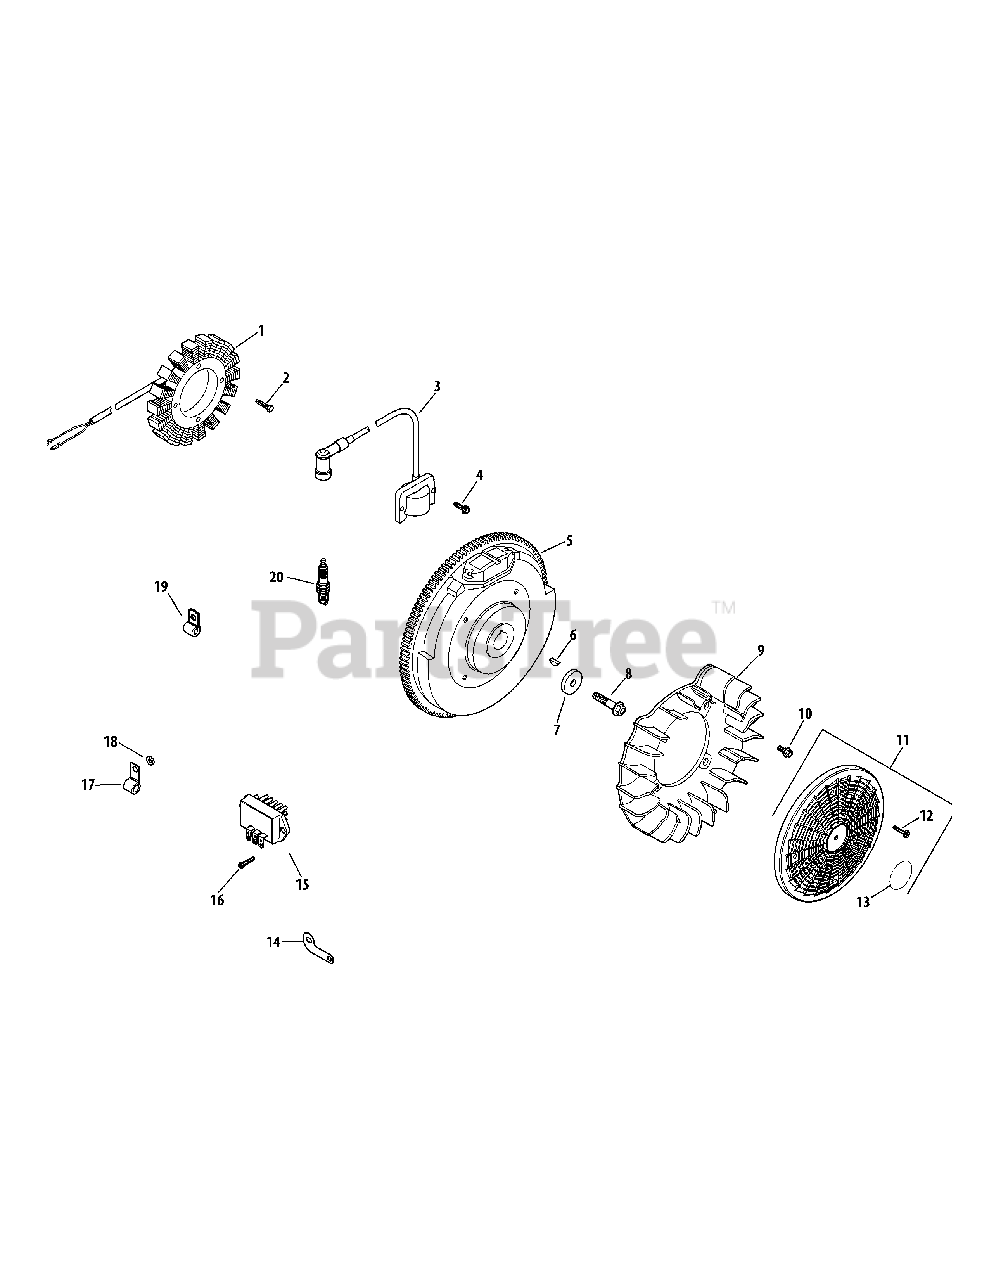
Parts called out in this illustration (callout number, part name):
1	15/20 Amp Stator Kit
2	Screw, M5 x 0.8 x 25
3	Ignition Module Kit (CDI Fixed)
4	Flange Screw, M5 x .8 X 20
6	Key, 3/16 X 5/8
7	Flat Washer, 13/32
8	Flange Screw, M10 x 1.5 x 45
10	Shoulder Bolt
11	Grass Screen Kit
12	Flange Screw, M4 x .7 X 25
13	Grass Screen Decal
14	Ground Strap Bracket
15	Rectifier Regulator
16	Hex Flange Screw
17	Cable Clip
18	Flat Washer, 1/4 x 1/2
20	Spark Plug (Standard)
